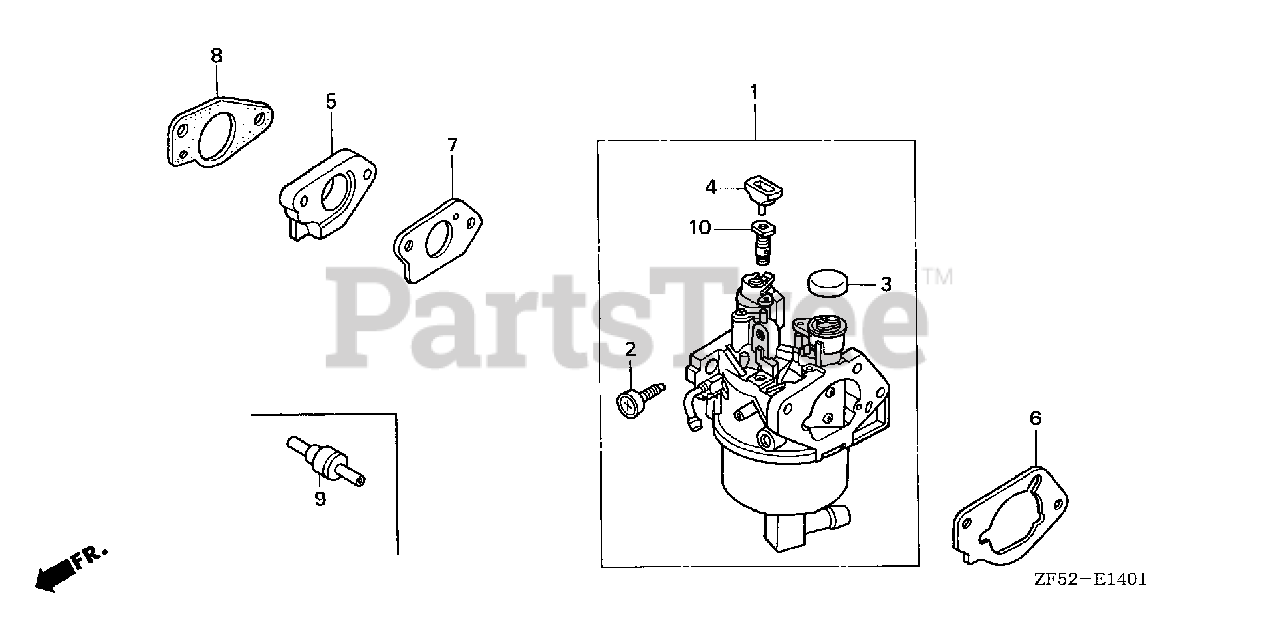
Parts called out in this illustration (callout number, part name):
1	CARBURETOR ASSY. (BEL7A C)
2	SCREW, THROTTLE STOP
3	CAP, CHOKE DUST
4	COLLAR, SETTING
5	INSULATOR, CARBURETOR
6	SPACER, CARBURETOR
7	GASKET, CARBURETOR
8	GASKET, INSULATOR
9	VALVE, DASHPOT CHECK
10	JET, PILOT (#45)
